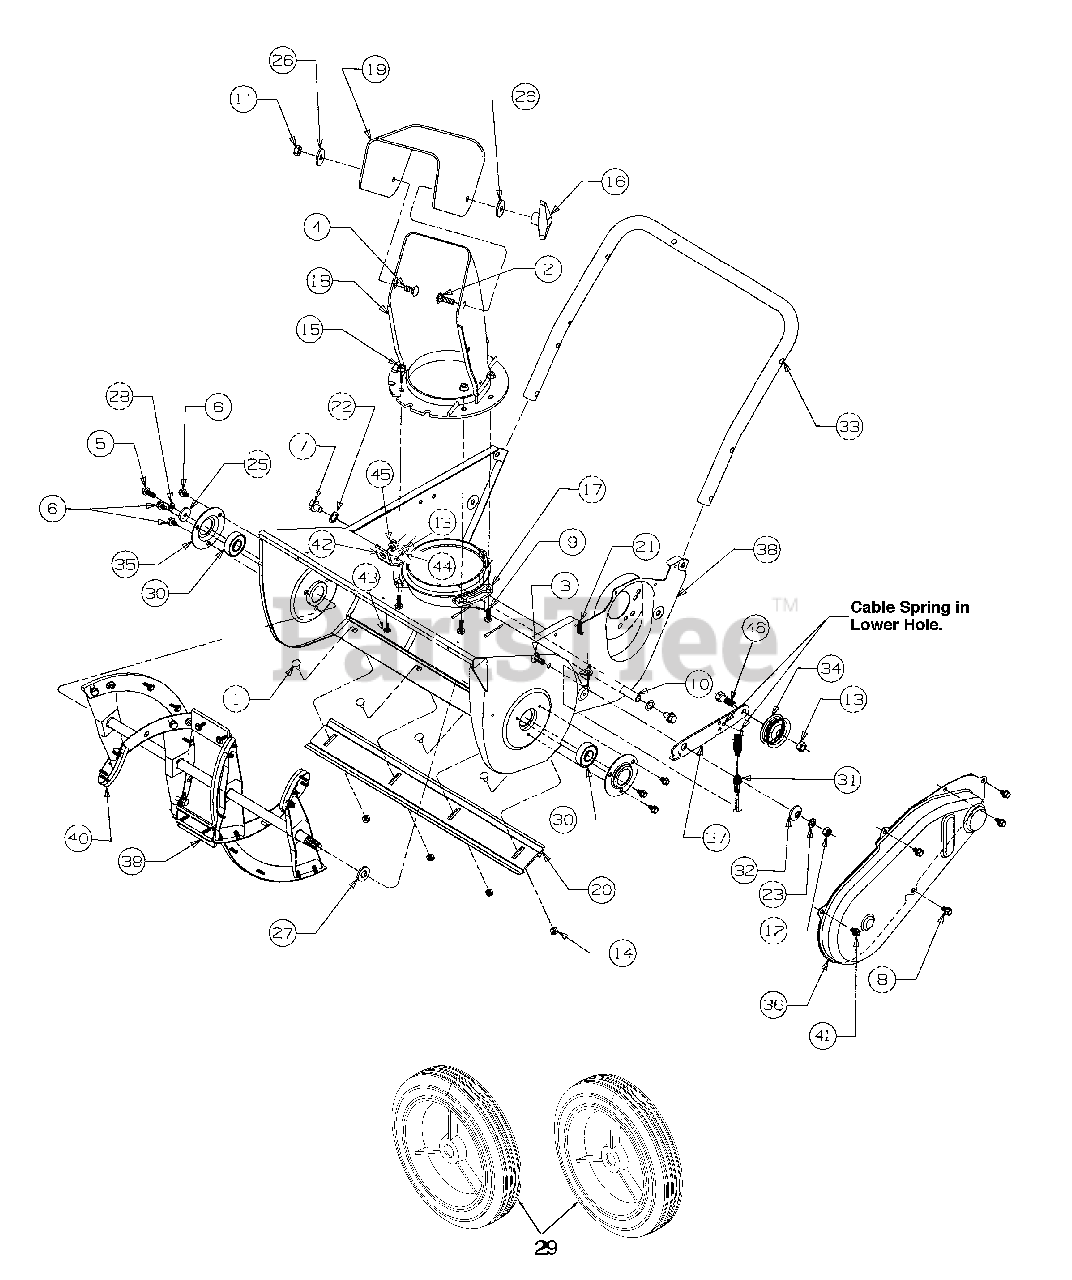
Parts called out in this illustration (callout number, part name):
1	Bolt, Carriage
2	Bolt, Carriage
3	Screw, Pan Head
4	Bolt, Carriage
5	Screw, Hex Washer
6	Screw, Hex Washer
7	Screw, Hex Washer
8	Screw, Hex Washer
9	Screw, Hex Cap
10	Axle
11	Nut, Hex Center Lock
13	Nut, Hex Lock
15	Nut, Hex Lock Flanged
16	Knob Assembly
17	Keeper, Chute
18	Chute, Lower
19	Chute, Upper
20	Shave Plate
21	Spring, Extension
22	Washer, Flat
23	Washer, Lock
25	Washer, Flat
27	Washer, Flat
28	Washer, Lock
29	Wheel Assembly, Beige
30	Ball Bearing
31	Cable, Clutch
32	Spacer, Shoulder
39	Auger Ass'y. Comp.
40	Auger Rubber Replacement
41	Screw, Hex Washer
44	Washer, Bell
45	Bushing
46	Screw, Cap
